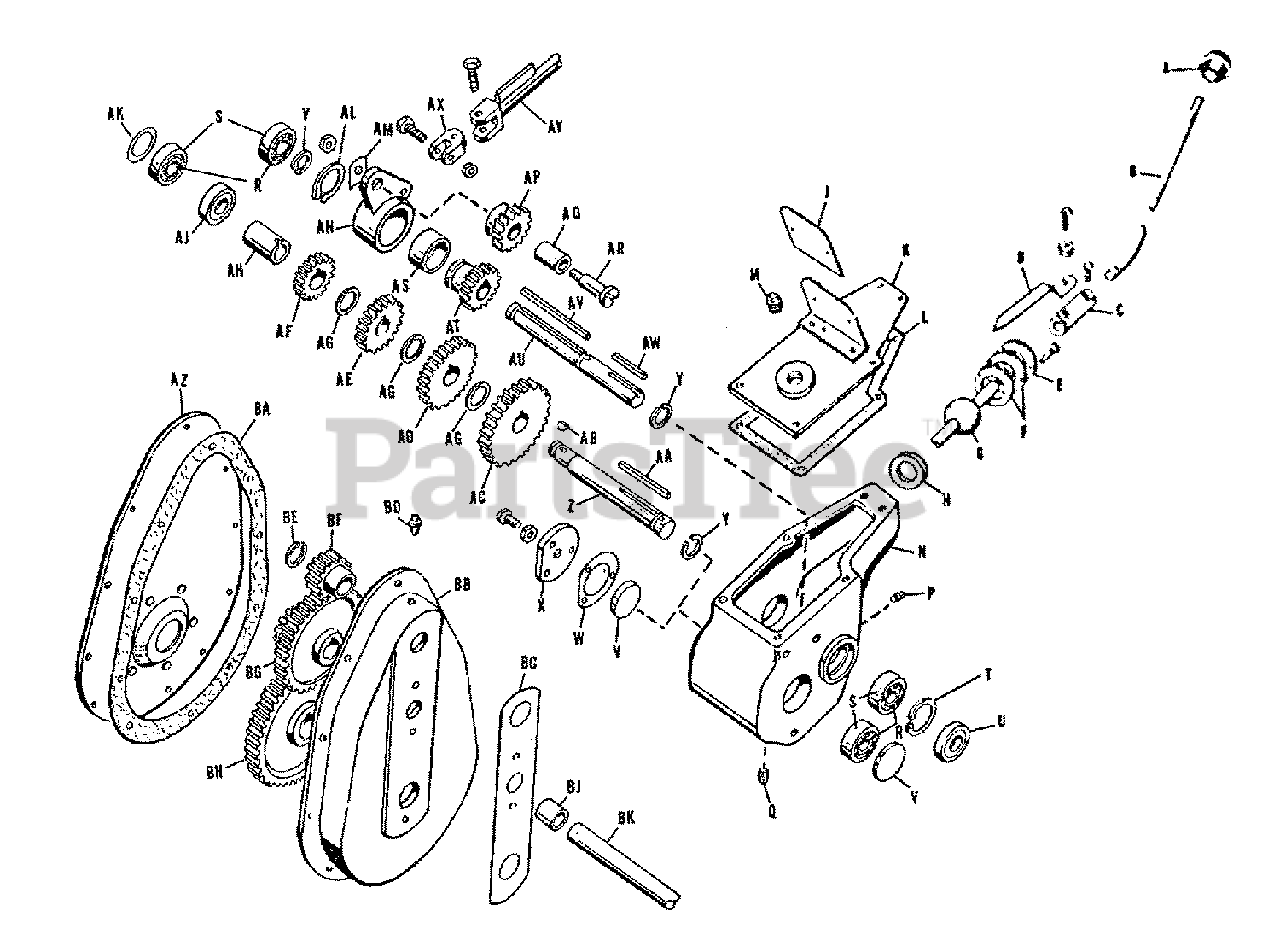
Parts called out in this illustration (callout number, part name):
A	BALL, Shift Lever
B	EXTENSION, Gear Shift Handle
C	COUPLING, Gear Shift Handle
D	POINTER, Shifter
E	RETAINER, Gear Shift Ball
F	SPACER, Shift Ball
G	BALL, Gear Shift
H	WASHER, Shift Ball
J	PLATE, Serial and Shift Instruction
K	COVER ASSEMBLY, Transmission Gear Case
L	GASKET, Transmission Gear Case Cover
M	PLUG, Filler
N	CASE, Transmission Gear
P	PLUG, Pipe, 1/8 Standard Square Head
Q	PLUG, Pipe, 1/4 Standard Square Head
R	CONE, Roller Bearing
S	CUP, Roller Bearing
T	RING, Retaining
U	SEAL, Oil
V	PLATE, Transmission Bearing Take-Up
W	GASKET, Adjusting Plate
X	PLATE, Transmission Bearing Take-Up
Y	RING, Retaining
Z	SHAFT, Tranmission Pinion
AA	KEY, Transmission Pinion Shaft
AB	KEY, Woodruff 5/32 x 5/8
AC	GEAR, "Reverse"
AD	GEAR, "Low"
AE	GEAR, "Medium"
AF	GEAR, "High"
AG	SPACER, Transmission Gear
AH	SPACER, Transmission Pinion Shaft
AJ	SEAL, Oil
AK	*SHIM, Transmission Bearing Cup
AL	RING, Retaining
AM	PLATE, Lock
AN	ARM, Transmission Rocker w/Bearing
AP	PINION, Rocker Arm with Bearing
AR	PIN, Rocker Arm Pinion
AS	BEARING, Rocker Arm
AT	GEAR, Transmission Slide
AU	SHAFT, Transmission Pulley
AV	KEY, Transmission Pulley Shaft
AW	KEY, Transmission Pulley
AX	PITMAN, Gear Shift
AY	CLEVIS ASSEMBLY, Pitman
AZ	COVER ASSEMBLY, Gear Case
BA	GASKET, Gear Case Cover
BB	CASE, Gear
BC	GASKET, Gear Case
BD	FITTING, Grease, Alemite #1641
BE	RING, Retaining
BF	PINION, Reduction
BG	GEAR ASSEMBLY, Cluster
BH	GEAR, Drive
BJ	BEARING, Intermediate Pinion
BK	SHAFT, Intermediate
